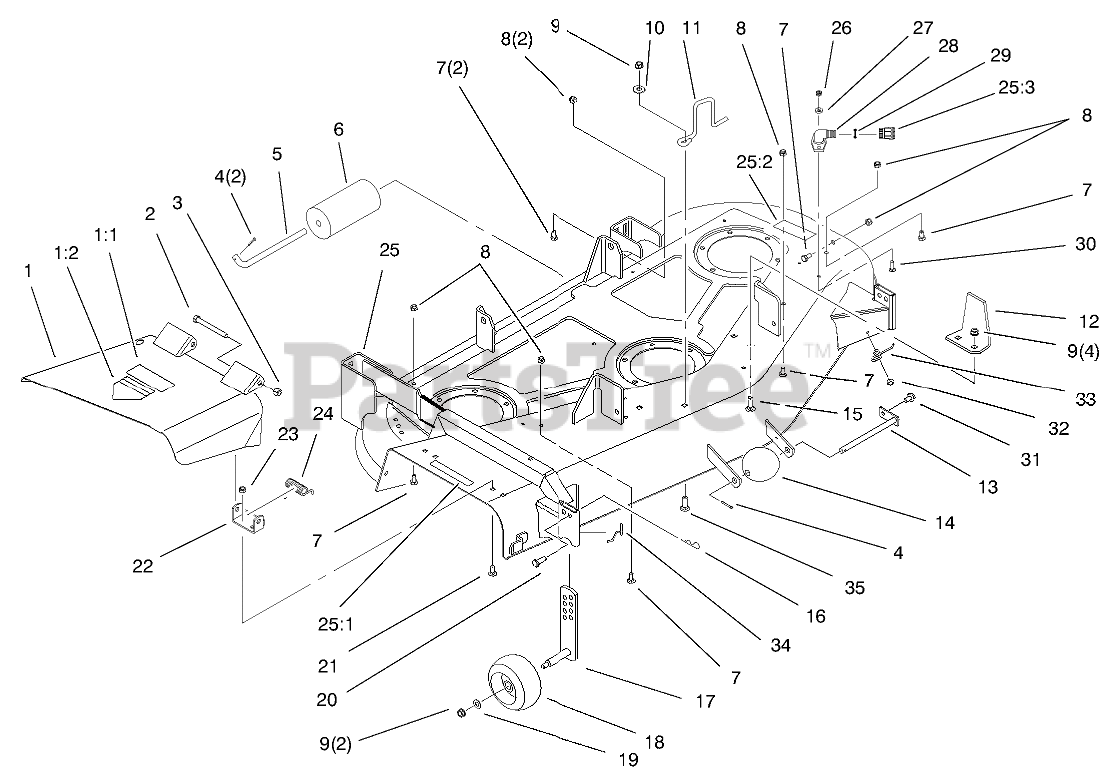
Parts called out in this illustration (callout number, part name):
1	Deflector ASM (Only On: 78370)
1	Deflector ASM (Only On: 78452)
1:1	Decal-Danger (Only On: 78370)
1:1	Decal-Danger (Only On: 78452)
1:2	Decal-Danger (Only On: 78370)
1:2	Decal-Danger (Only On: 78452)
2	SCREW-HH
3	NUT-HEX
4	PIN-COTTER
5	SHAFT-ROLLER, REAR
6	ROLLER-DECK
7	SCREW-HH
8	NUT-LOCK, NI
9	NUT-LOCK, NI
10	WASHER
11	GUIDE-BELT
12	Bracket Guide
13	SHAFT ASM
14	ROLLER
15	BOLT-CARR
16	PIN-HAIR
17	GAGE-WHEEL
18	WHEEL-GAGE
19	WASHER-FLAT
20	PIN-CLEVIS
21	SCREW-CARR
22	BRACKET-PIVOT
23	NUT-LOCK, NI
24	SPRING
25	Deck ASM (Only On: 78370)
25	Deck ASM (Only On: 78452)
25:1	Decal-Danger (Only On: 78370)
25:1	Decal-Deflector Danger (Only On: 78452)
25:2	Decal-Danger (Only On: 78370)
25:2	Decal-Danger (Only On: 78452)
25:3	CONNECTOR-HOSE
26	Nut-Lock (Only On: 78452)
27	Washer-Flat (Only On: 78452)
28	Fitting-Washout (Only On: 78452)
29	0-Ring (Only On: 78452)
30	Bolt-CARR (Only On: 78452)
31	SCREW-HWHTF
32	SCREW-HHFTF
33	SPRING-GAGE WHEEL, LH
34	SPRING-GAGE WHEEL, RH
35	SCREW-CARR
